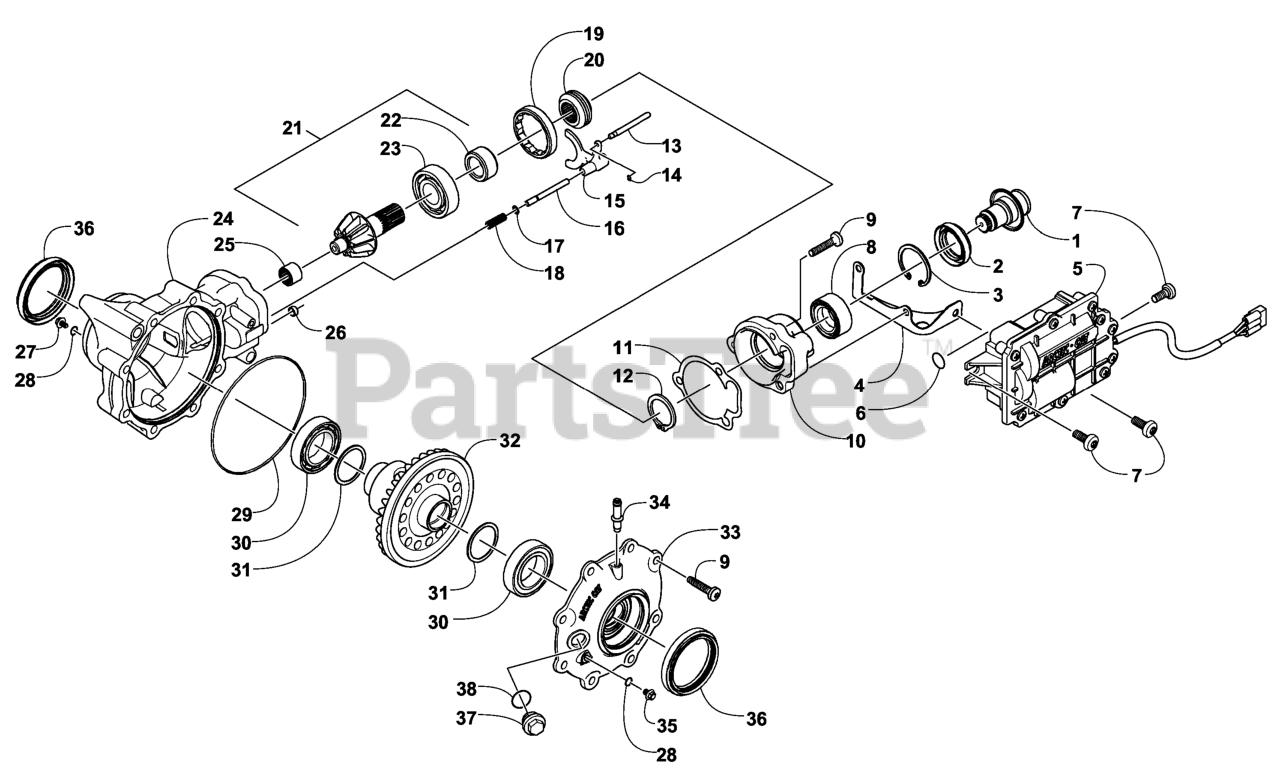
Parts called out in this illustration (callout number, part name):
1	SHAFT-INPUT
3	RING-RETAINING
4	BRACKET-ACTUATOR
5	ACTUATOR ASM
6	O-RING, ACTUATOR
7	BOLT-FLANGE
8	BEARING-BALL, DOUBLE ROW
9	BOLT-FLANGE
10	HOUSING-PINION
11	GASKET-FLANGE
12	RING-RETAINING
13	PUSHROD-SELECTOR
14	RING-RETAINING
15	FORK-SELECTOR
16	SHAFT-SHUTTLE
18	SPRING-RETURN, 4WD
19	COLLAR-LOCK
20	COUPLER-DRIVE
21	PINION
22	COLLAR-RETAINING
23	BEARING-BALL, RADIAL
24	HOUSING-GEARCASE, FRONT
25	BEARING-NEEDLE
26	PIN-DOWEL
27	PLUG-DRAIN
30	BEARING-BALL
32	GEAR-36 T, 4.0
33	COVER-GEARCASE
34	FITTING-BARB, STRAIGHT
35	PLUG-OIL LEVEL
36	SEAL-GEARCASE
37	PLUG-FILL
